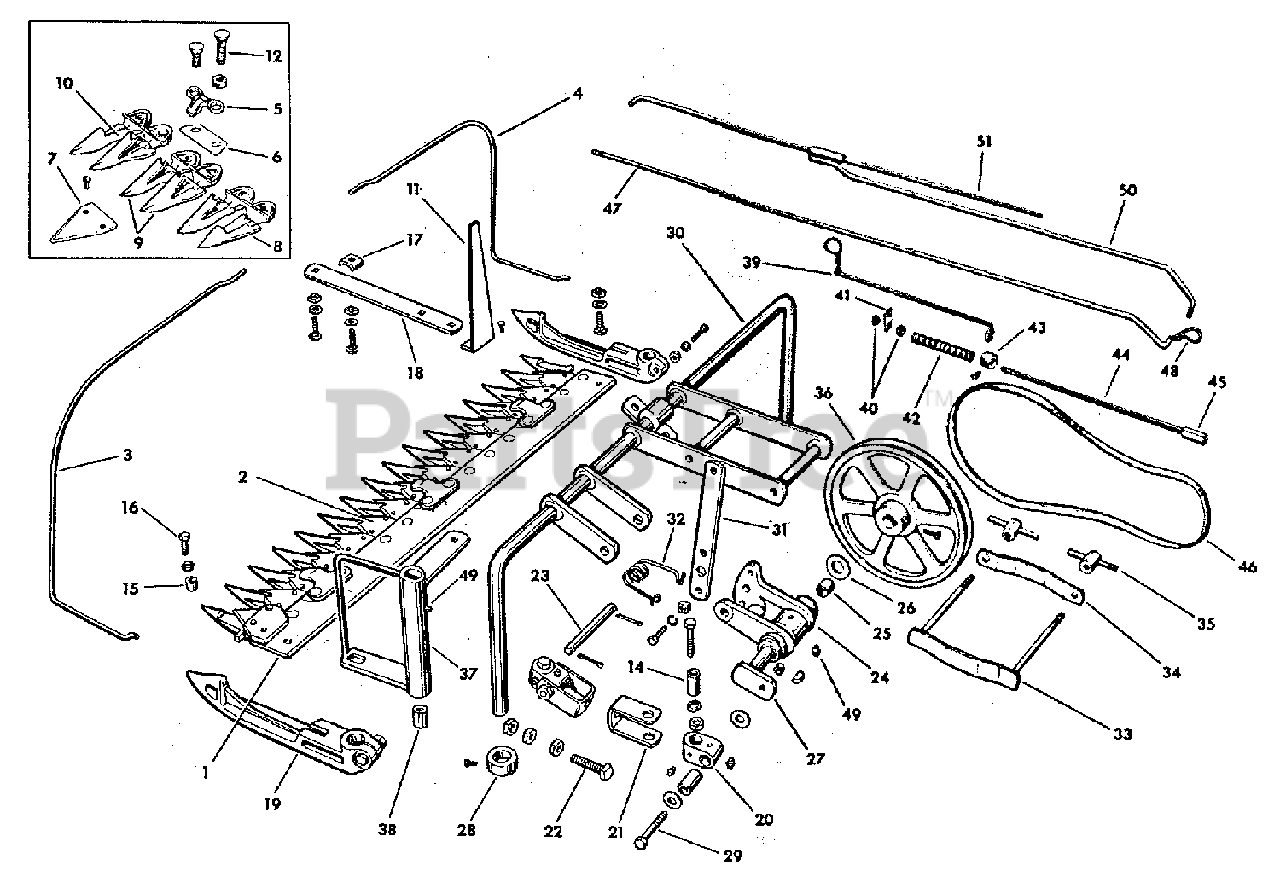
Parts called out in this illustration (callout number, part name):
1	BAR, Cutter
2	SICKLE, Complete w/Head
3	GRASS FINGER, Left
4	GRASS FINGER, Right
5	CLIP, Sickle
6	WEAR PLATE
7	SICKLE SECTIONS (15 Sections and 30 Rivets in box)
8	END GUARD, Left
9	TWIN GUARD
10	END, Right
12	GUARD BOLT, Long
13	GUARD BOLT, Short
14	BEARING, Pivot Block
15	BEARING, Sickle Head
17	CLAMP, Grass Finger
18	BRACKET, Grass Finger
19	SHOE, Sickle Bar
20	PIVOT BLOCK
21	CLEVIS, Pitman
23	PIN, Hinge
24	BRACKET, Bearing
25	CRANKSHAFT, Bronze Bushing
26	WASHER, Spacer Thrust
27	CRANKSHAFT
28	COLLAR, Set, 7/8
30	FRAME, Sickle Bar
31	ARM, Clutch
32	SPRING, Belt Release
33	CLAMP, Hitch
34	SIDE PLATE, Hitch
35	NUT, Wing, Complete
36	SHEAVE, 8", Iron or Steel
37	CRANK, Sickle
39	ROD, Clutch
43	COLLAR, Set
44	CLUTCH ROD, Adjustable
45	NUT, Clutch Rod
46	BELT, 33" Circle
47	CLUTCH ROD, Long
48	CLIP, Spring
50	ROD, Lower Idler
51	ROD ASSEMBLY, Upper
